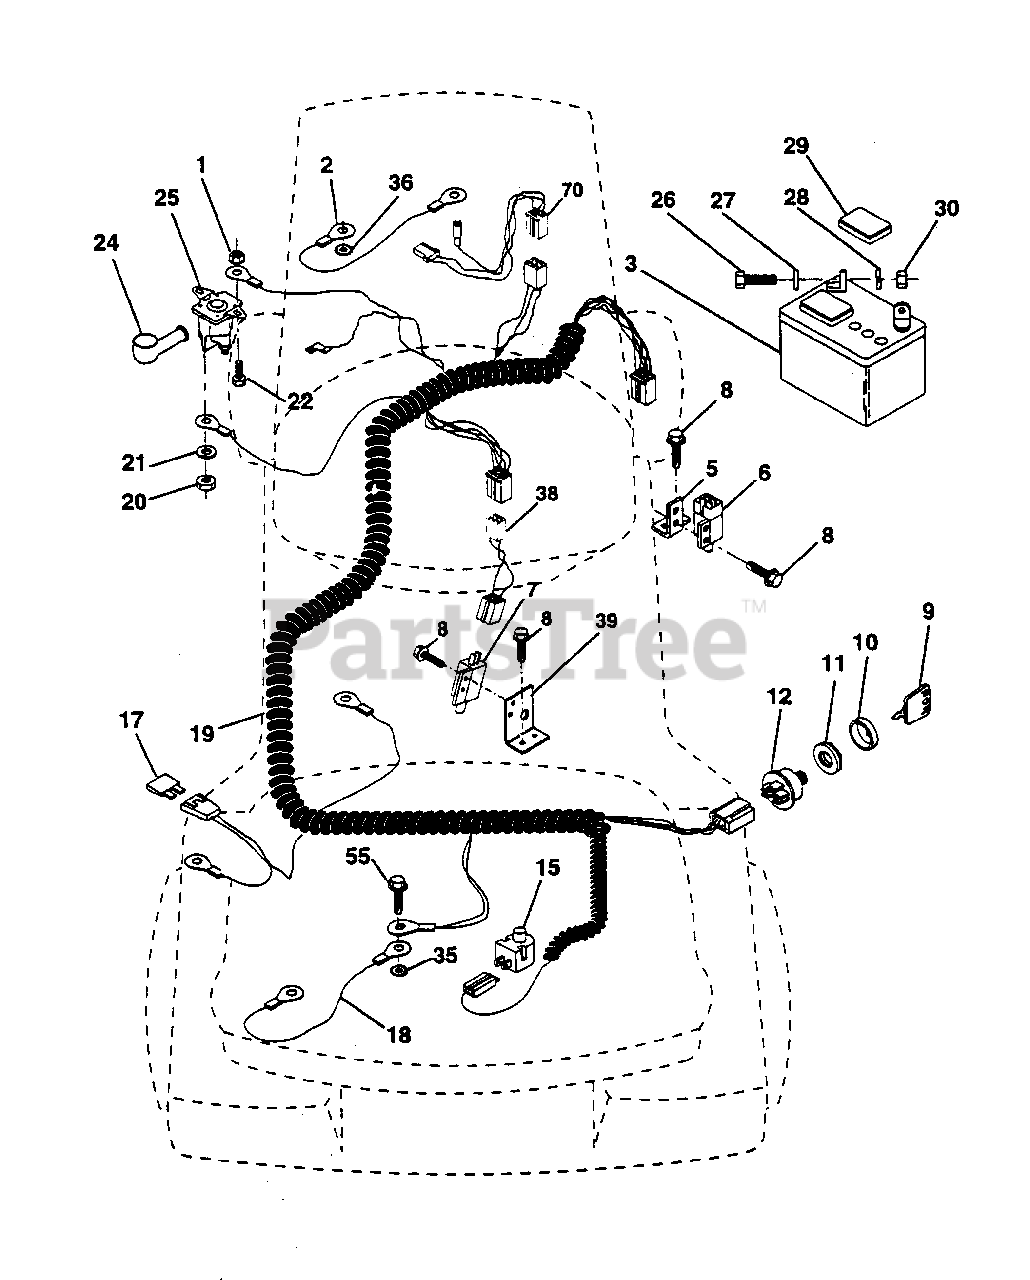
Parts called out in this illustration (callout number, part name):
1	Nut, Hex Keps 1/4-20
2	Assembly, Cable
3	Battery
5	Bracket, Switch
6	Switch, Interlock (4-terminal)
7	Switch, Interlock (2-terminal)
8	Screw, Hex Hd. Tap #10-24 x 1/2
9	Key, Steel Delta
10	Cover, Key Ignition
11	Nut, Ignition
12	Switch, Ignition
15	Switch, Plunger
18	Assembly, Cable
19	Harness, Ignition
20	Nut, Hex Jam 1/4-20
21	Washer, Lock 1/4
22	Bolt, Fin. Hex 1/4-20 UNC x 1/2 Gr. 5
24	Cover, Terminal
25	Solenoid
26	Bolt, Hex Hd. 1/4-20 UNC x 3/4
27	Washer 9/32 x 5/8 x 16
28	Washer, Lock 1/4
30	Nut, Fin. Hex 1/4-20 UNC
35	Washer Lock Ext. Tooth 5/16
36	Washer Lock Inter. Tooth 1/4
38	Adapter Harness
39	Bracket Switch Clutch
40	Screw, Thdrol 5/16-18 x 1/2
70	Harness Engine
